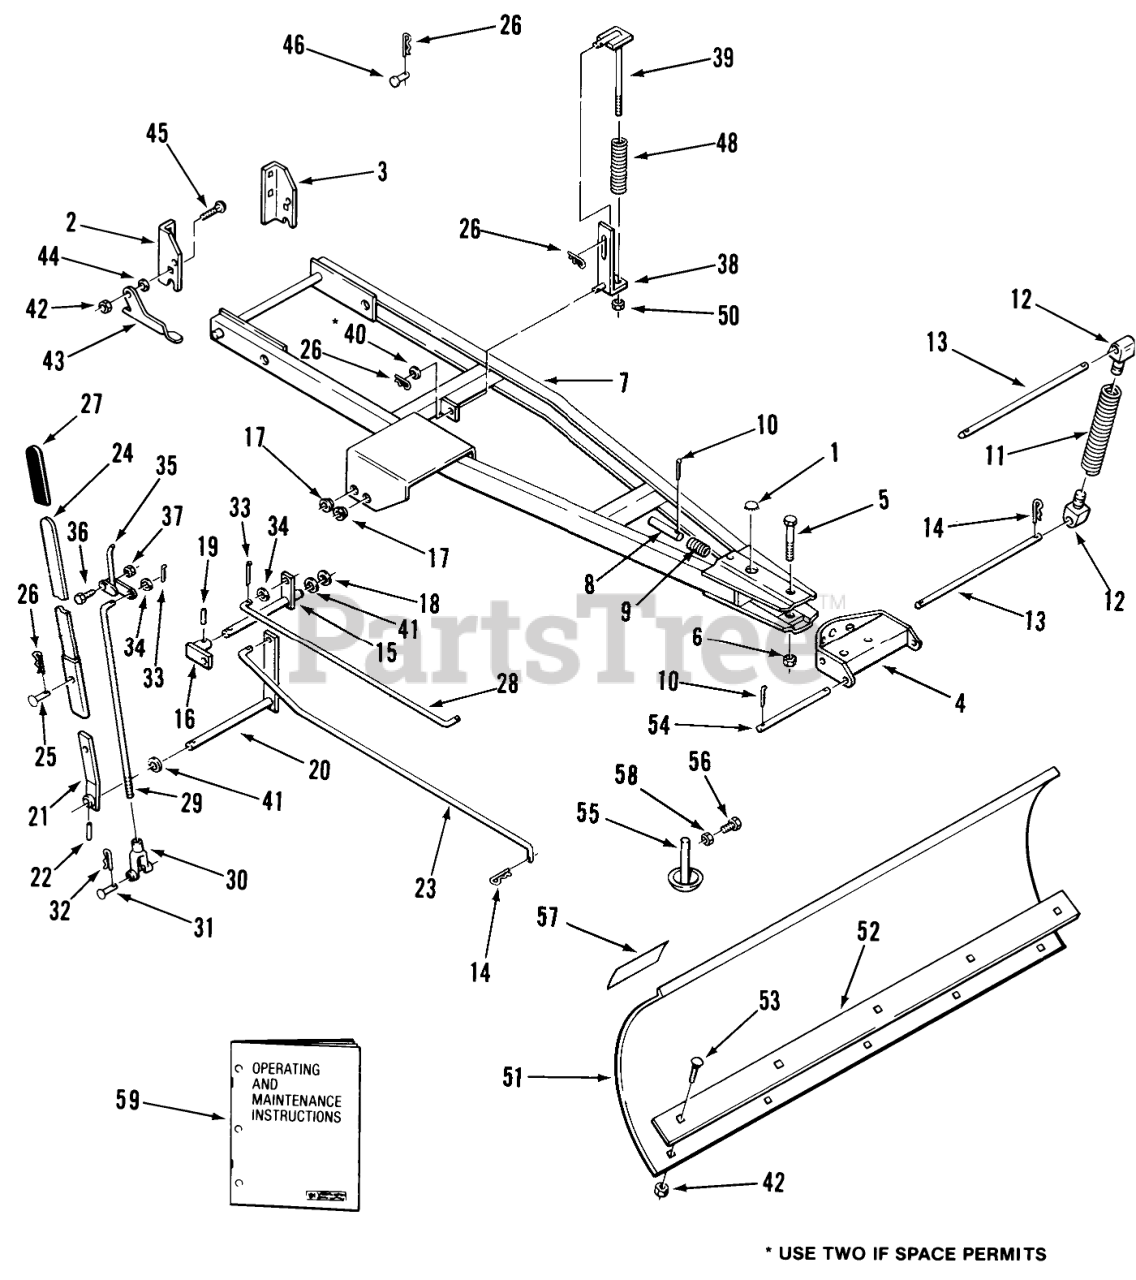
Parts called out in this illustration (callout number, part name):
1	PLUG
2	BRACKET RH R
3	BRACKET LH R
4	Sector and Channel
5	Bolt
6	Nut
8	Index Pin
9	SPRING-COMPRESSION
11	Spring
12	Lug
13	ROD-TRIP RETURN
14	Hairpin
15	Bushing
16	Sat Collar
17	BUSHING
18	Snap Ring
19	SPIROL PIN 3/8X1 3/4
20	Assembly-Blade Index Arm
21	Assembly-Handle Bar
22	SPIROL PIN 3/8X1 1/2
23	Blade Control Rod
24	HANDLE ASM
25	Pin-Clevis
26	Hairpin Cotter
27	GRIP
28	ROD LOWER
29	ROD UPPER INDEX
30	YOKE
31	Pin
33	Cotter Pin
35	Assembly Index Lever
36	Bolt
37	Nut
38	Assembly-Lift Bar
39	Assembly Lift Rod
40	Washer
41	Shim Washer
42	NUT
43	PLATE-LATCHING
44	Washer
45	BOLT
46	Pin
48	SPRING
50	Nut
51	Blade Assembly
52	PLATE-BLADE EDGE
53	Bolt-Carriage
54	ROD-LOWER
55	SKID SHOE ASSY R
56	Screw-Set
57	DECAL-WARNING
58	Nut
59	Operating and Maintenance Instructions
